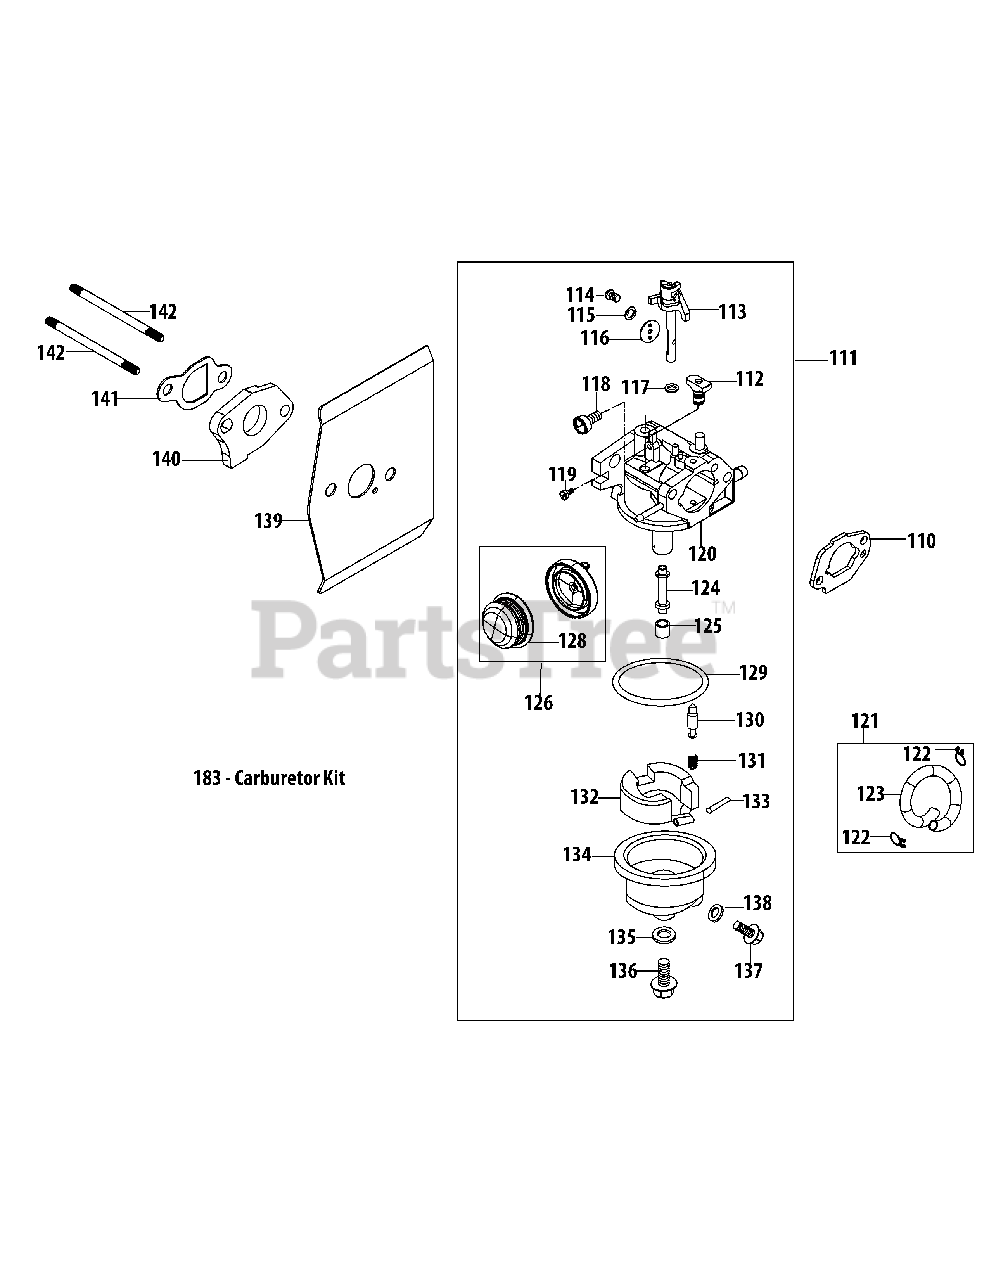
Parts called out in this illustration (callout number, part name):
110	Carburetor Gasket Plate
111	Carburetor Assembly
112	Idle Jet Assembly
113	Throttle Shaft
114	Screw M3X5 Throttle Plate
115	Throttle Plate Lock Washer
116	Throttle Plate
117	Throttle Shaft Fiber O-Ring
118	Idle Speed Adjusting Screw
119	Idle Mixture Screw
120	Carburetor Body
121	Primer Hose Assembly
122	Primer Hose Clamp
123	Primer Hose
124	Emulsion Tube
125	Main Jet
126	Primer Assembly
128	Primer Bulb
129	Fuel Bowl O-Ring
130	Needle Valve
131	Needle Valve Spring
132	Float
133	Float Pin
134	Fuel Bowl
135	Fuel Bowl Gasket
136	Fuel Bowl Mounting Bolt
137	Fuel Drain Plug
138	Fuel Drain Plug Gasket
139	Carburetor Gasket
140	Carburetor Insulator
141	Carburetor Insulator Gasket
142	Carb Stud M6X92
183	Carburetor Repair Kit - Major
